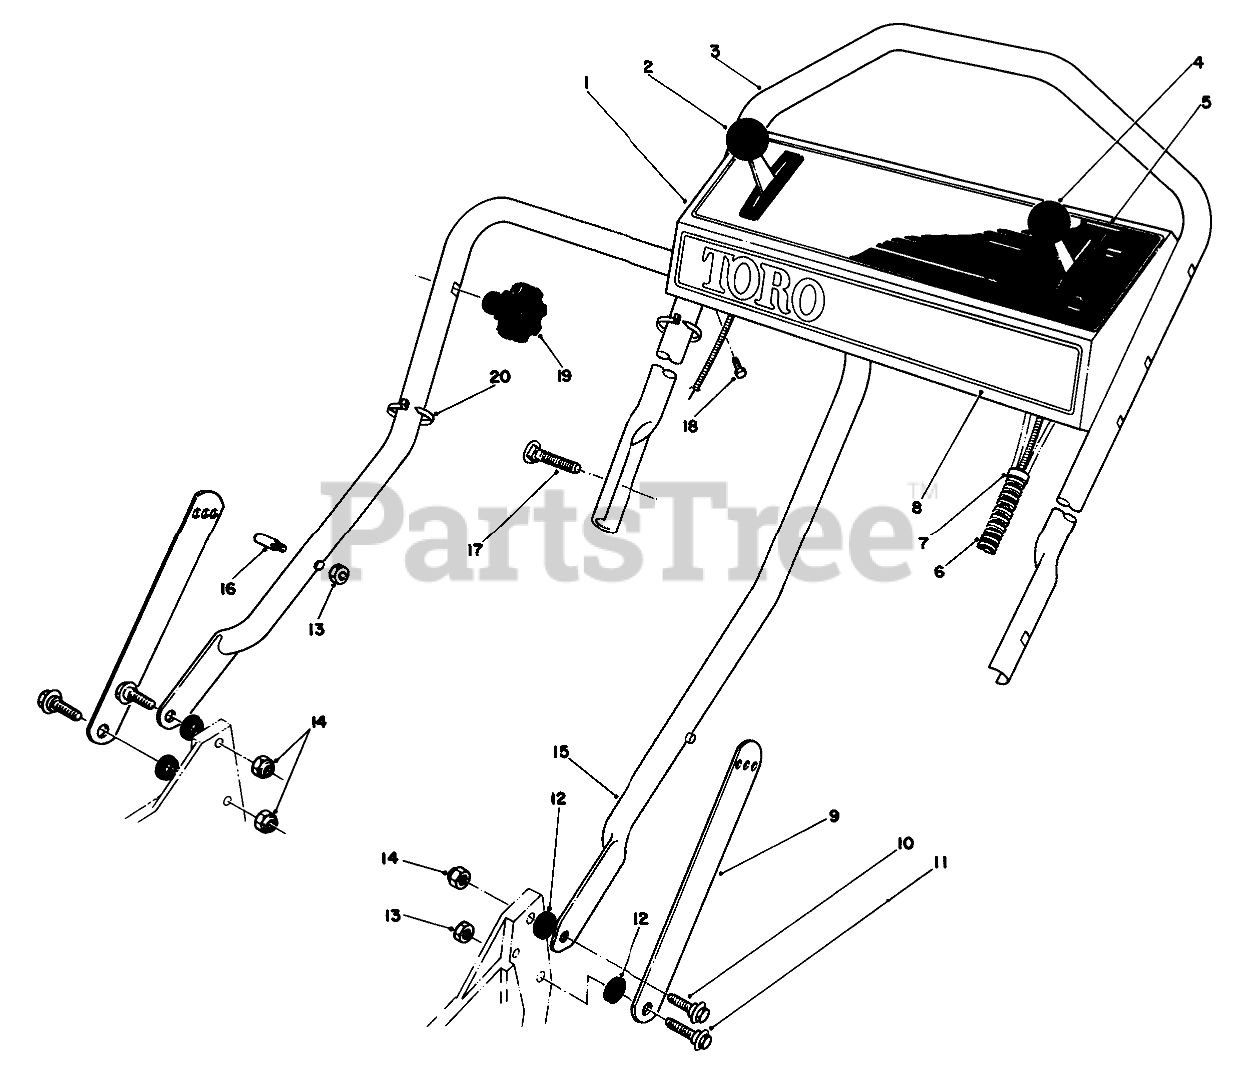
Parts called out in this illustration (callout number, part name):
1	Panel-Control (lnc. Ref. #5)
2	GROUND SPEED CONTROL
3	Handle-Upper
4	THROTTLE CONT-SERVICE
5	Decal-Instruction Panel
6	CONTROL CABLE COVER
7	FITTING-RING
8	Decal-Toro
9	Handle Latch
10	SCREW-SHOULDER
11	SCREW-SHOULDER
12	SPACER
13	NUT-LOCK, NI
14	NUT-LOCK, NI
15	Handle-Lower
16	HANDLE PIN
17	5/16-18 X 2 HNDLE SCREW
18	SCREW-HWHTF
20	TIE-CABLE
